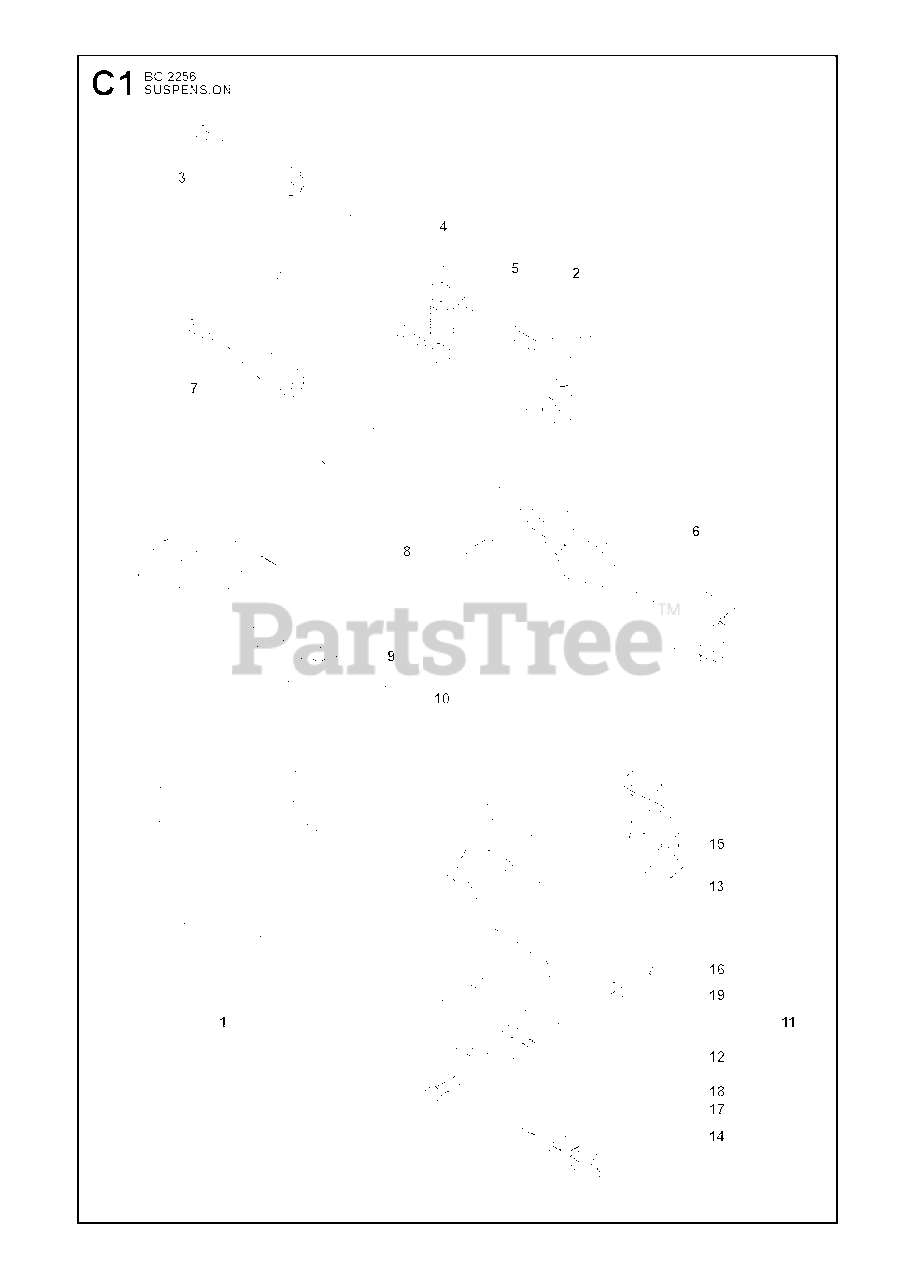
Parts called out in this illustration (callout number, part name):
5	PARALLEL PIN
6	ANTIVIBE ELEMENT
7	SCREW IHSCFM
12	BAND
13	LOOP
16	NUT
18	SCREW
19	WASHER 5.3X12
